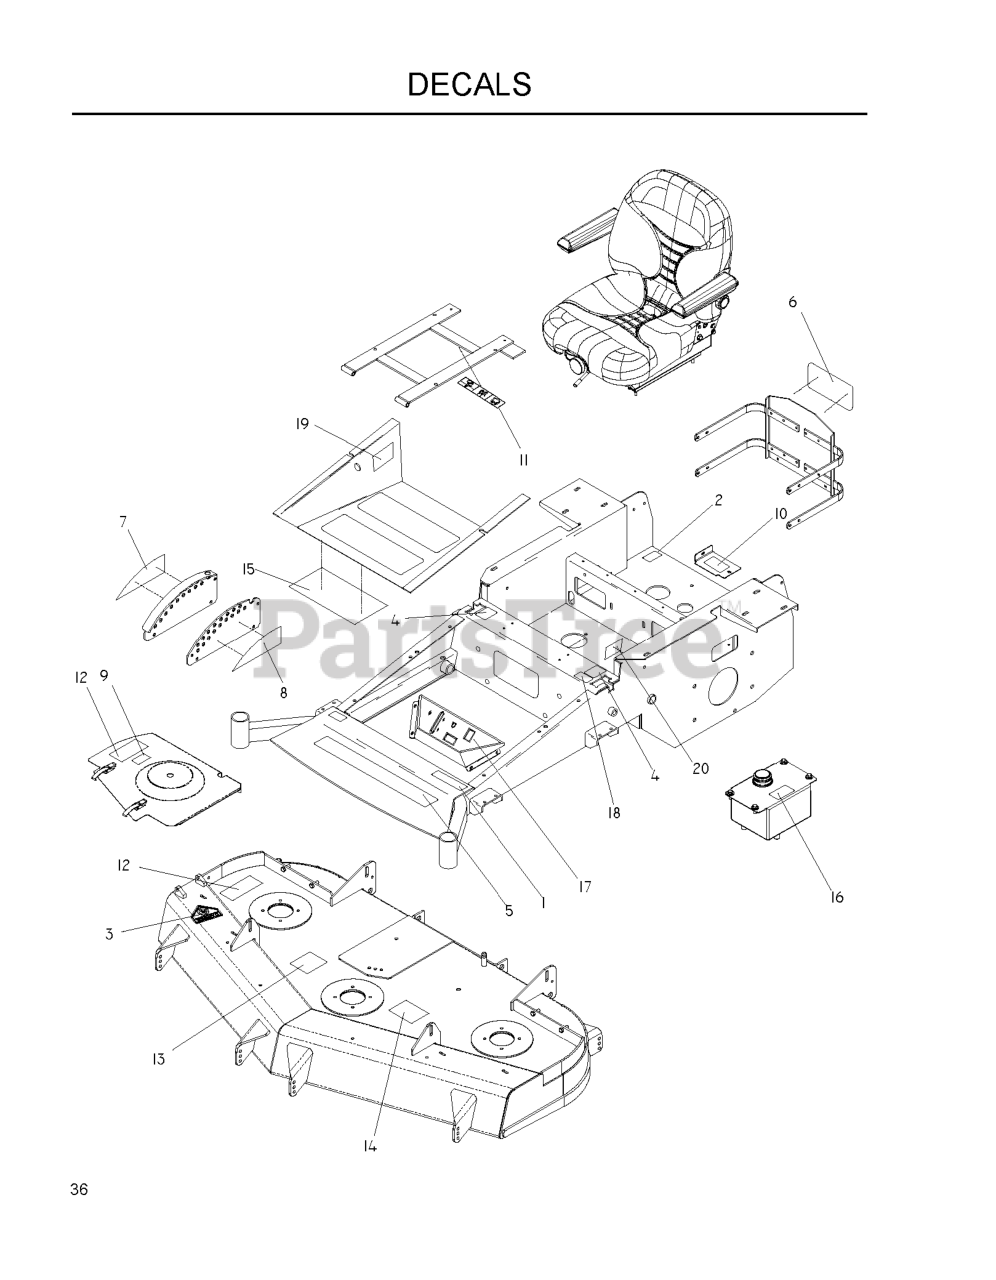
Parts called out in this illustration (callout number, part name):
1	DECAL, LZ30
1	DECAL, LZ6130
1	DECAL, LZ5227
1	DECAL, LZ6127
1	DECAL, LZ7230
2	DECAL, PROP. 65
3	DECAL, CPSC
4	DECAL, MOTION CONTROL
5	DECAL, HUSQ 15" BLUE
6	DECAL, CROWN H 5-1/4 SILVER
7	DECAL, HEIGHT
8	DECAL, HEIGHT
9	DECAL, NO STEP
10	DECAL, BELT DRIVE
11	EURO DECAL-BATTERY WARNIN6
12	DECAL, EURO SEVERING
13	DECAL, ANTI SCALP
14	DECAL, BELT ROUTING
15	DECAL, SERVICE
16	DECAL, OIL TANK
17	DECAL, CONSOLE
18	DECAL, F.S.T.
19	DECAL, WARNING
20	DECAL, RELAYS
